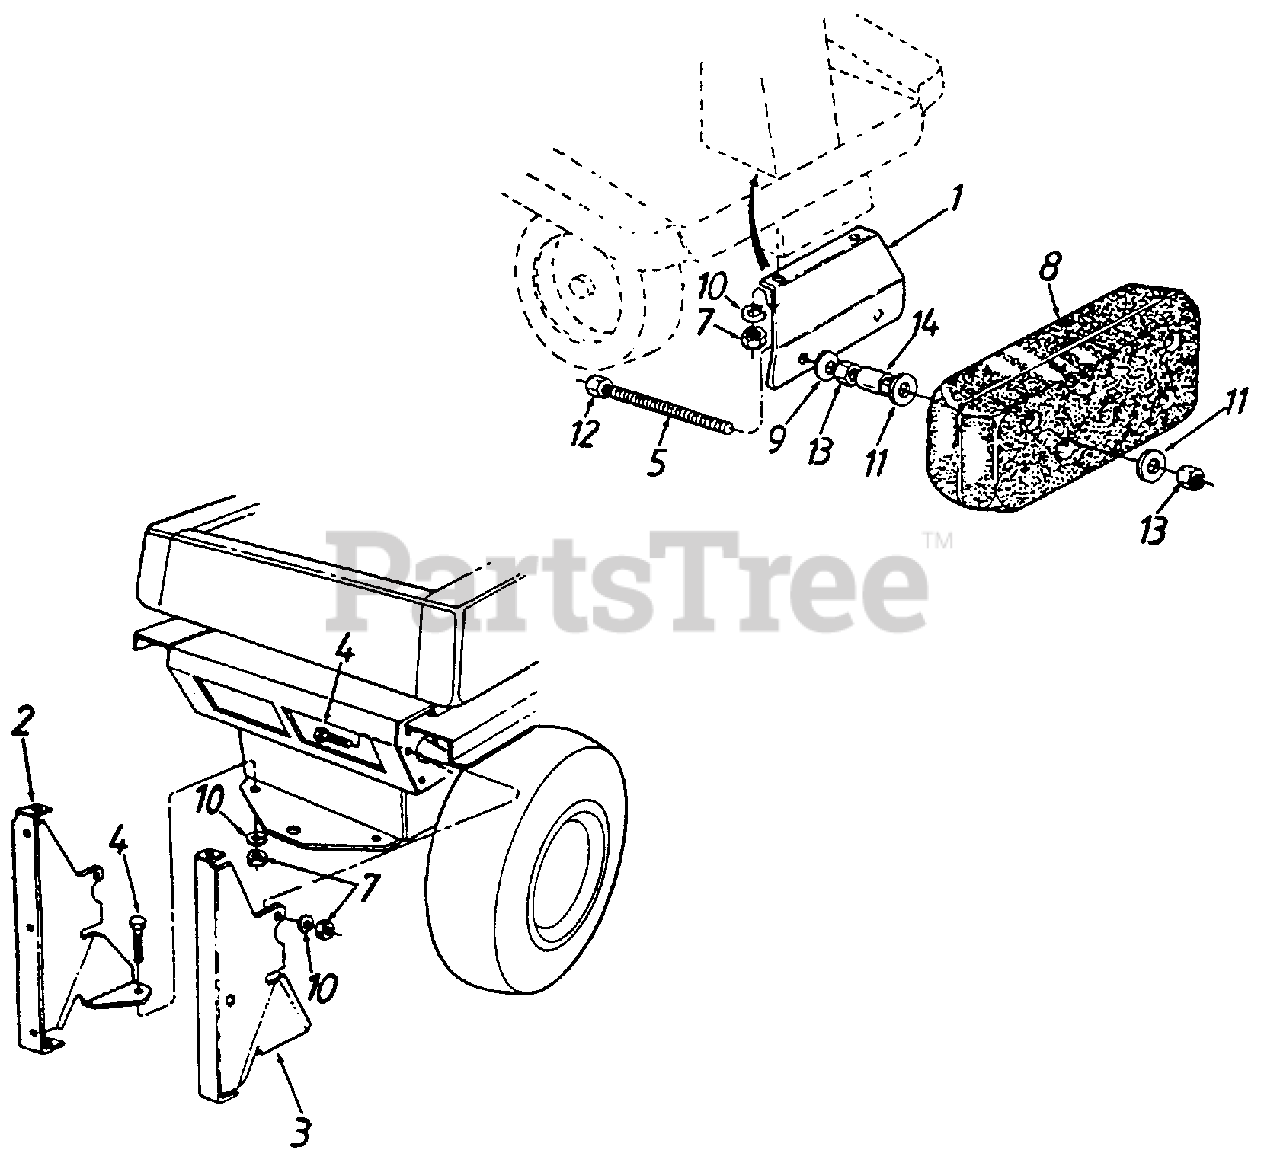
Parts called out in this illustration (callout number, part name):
3	Catcher Support Brkt.-L.H.
4	Hex Bolt 5/16-18 x 1.0" Lg.
5	Stud 7/16-14 x 5-5/8" Lg.
7	Hex Nut 5/16-18 Thd.
8	Front Counterweight
9	Bell-Wash. 5/16" I.D.
10	L-Wash. 5/16" I.D.
11	Fl-Wash. .45" I.D.
12	Hex L-Nut 7/16-14 Thd.
13	Hex Nut 7/16-14 Thd.
14	Spacer
